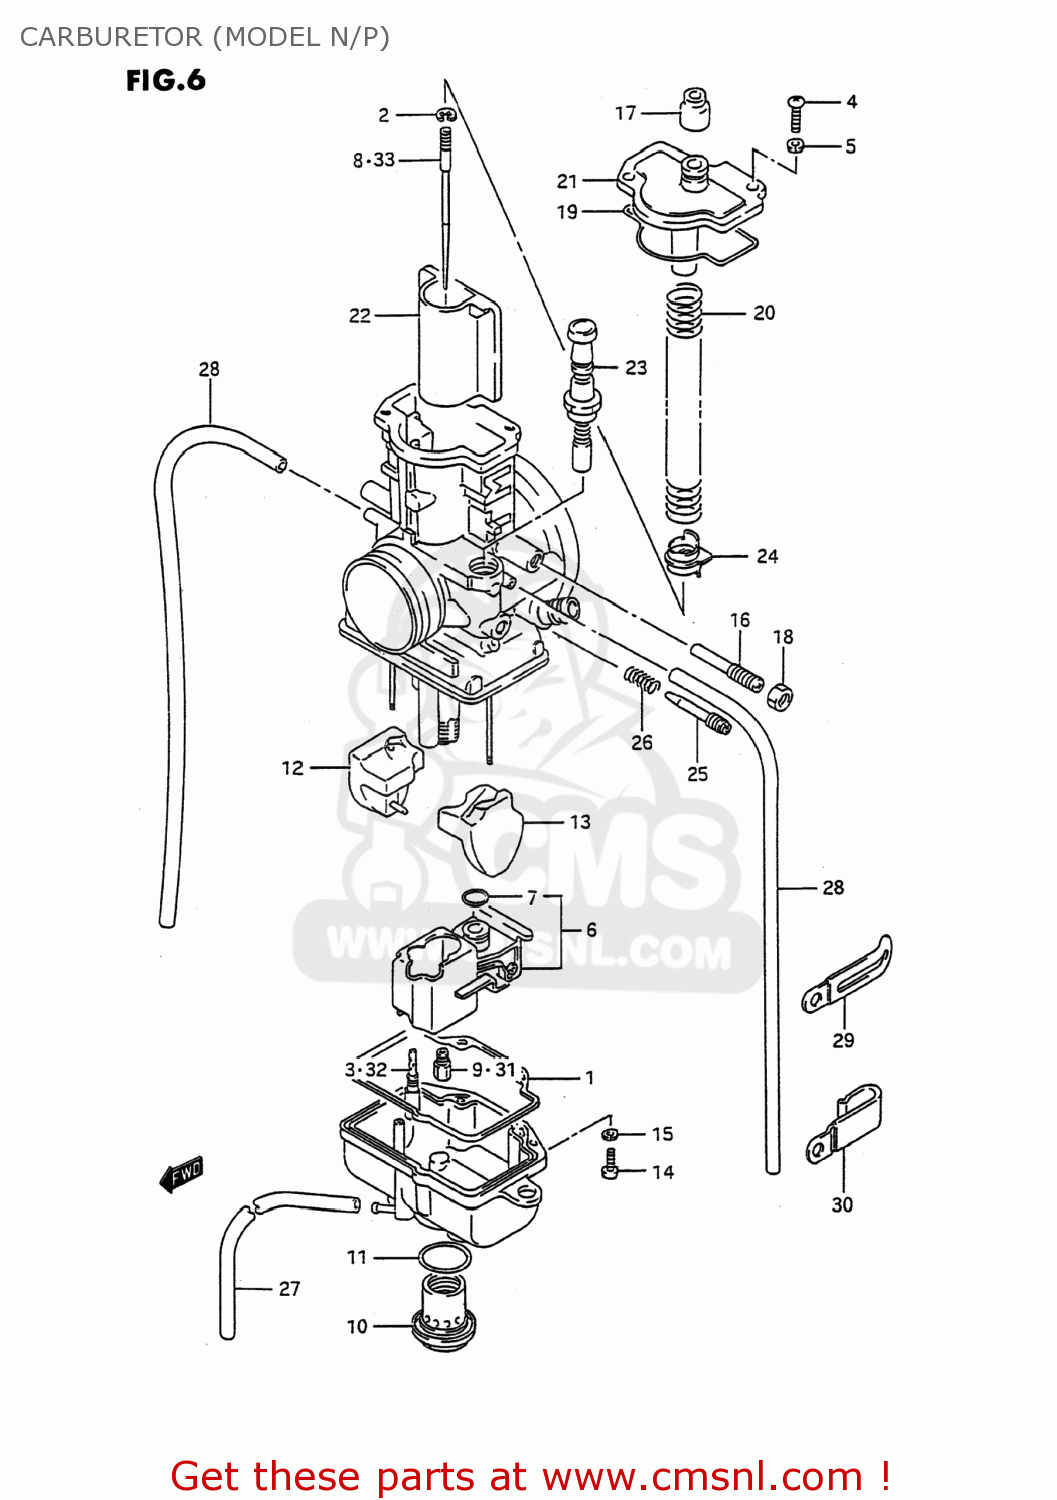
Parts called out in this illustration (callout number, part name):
1	O RING,FLOAT CHAMBER
2	CLIP,NEEDLE
3	JET,PILOT(50)
4	SCREW
5	LOCK WASHER
6	VALVE ASSY,NEEDLE
7	O-RING,NEEDLE VALVE
8	NEEDLE JET (6BEJ6-66)
9	JET,MAIN(320)
10	CAP,DRAIN
11	O RING
12	FLOAT,R
13	FLOAT,L
14	SCREW
15	LOCK WASHER
16	ADJUSTER
17	CAP
18	NUT
19	O RING,TOP CAP
20	SPRING
21	CAP,TOP
22	VALVE,PISTON
23	PLUNGER ASSY
24	RING
25	SCREW,AIR
26	SPRING
27	HOSE(3X5X600)
28	HOSE(3.5X6.5X600)
29	CLAMP
30	CLAMP
31	JET,MAIN(330)
32	JET,PILOT(45)
33	NEEDLE JET (6BEJ6-65)
